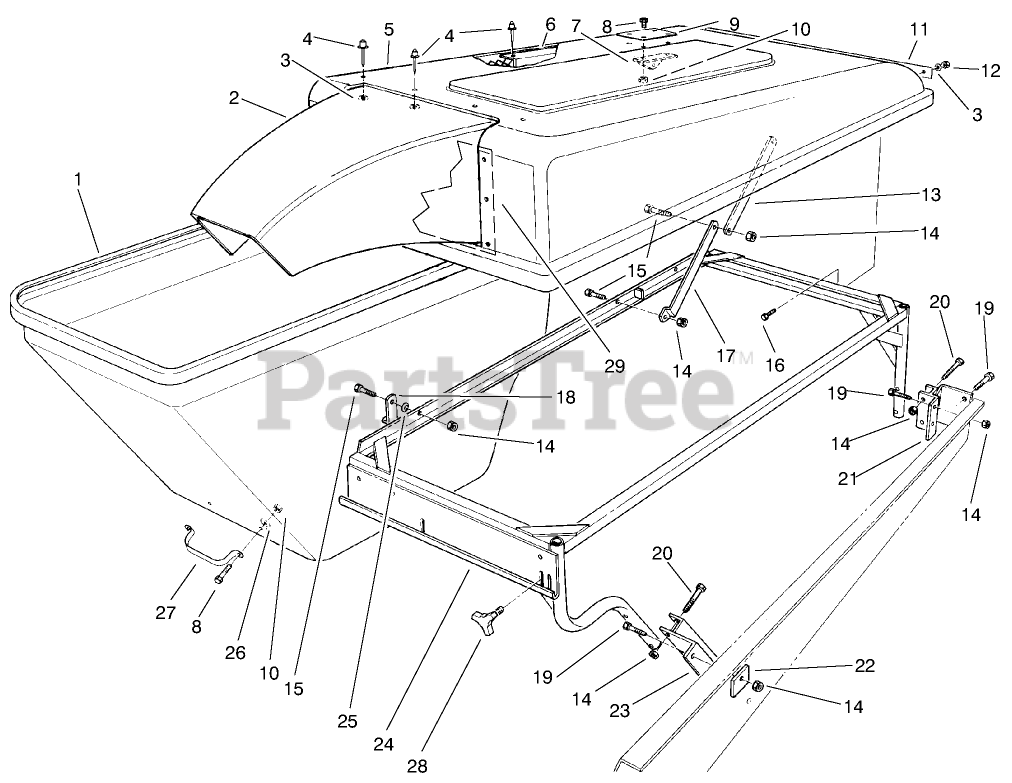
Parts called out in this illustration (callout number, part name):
1	BAGGER HOPPER
2	BAGGER SNOUT
3	WASHER-FLAT
4	NUT-LOCK
5	HOOD-GRASS CATCH
6	Bagger Screen
7	Pivot
8	SCREW-HH
9	HOOD PLATE
10	NUT-LOCK, NI
11	HINGE PLATE
12	NUT-LOCK, NI
13	Link
14	NUT-LOCK, NI
15	SCREW-HH
17	Link-Bag
18	Latch-Hopper
19	SCREW-HH
20	SCREW-HH
21	Bracket-Rear
22	Plate-Reinforcing
23	Bracket-Front
24	HOPPER FRAME WA
25	WASHER-SPRING
26	WASHER-FLAT
27	Handle
29	NUT-LOCK, NI
